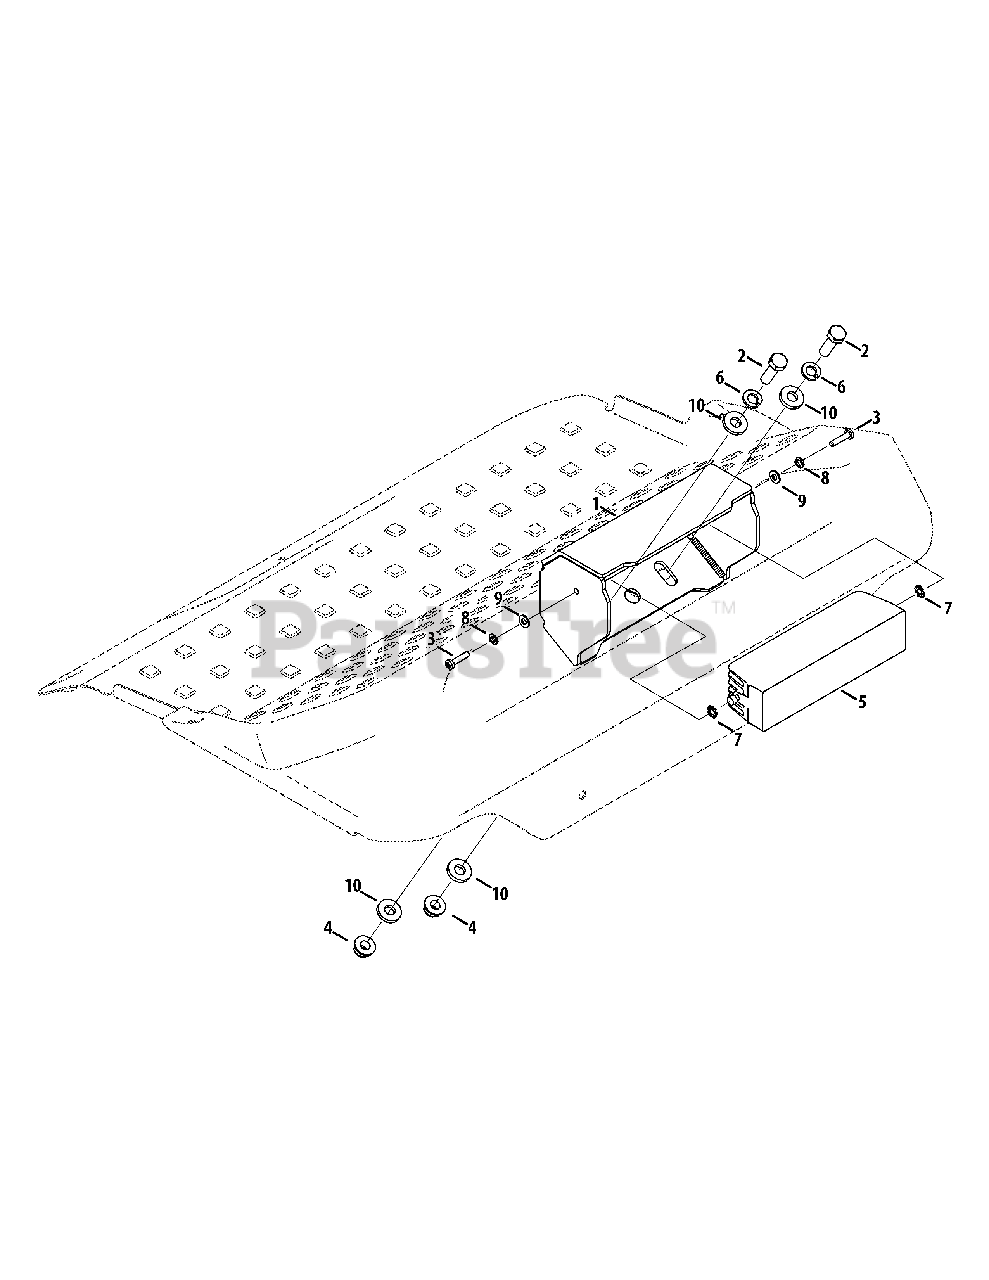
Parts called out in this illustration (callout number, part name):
1	Welded Headlight Bracket
2	Hex Screw, 5/16-18 x 1.00
3	Machine Screw, #8-32 x .750
4	Flange Lock Nut, 5/16-18
5	LED Light Housing Assembly
6	Lock Washer, 5/16
7	External Tooth Lock Washer, #10
8	Lock Washer, #10
9	Flat Washer, .203 x .403 x .040
10	Flat Washer, .344 x .750 x .120
